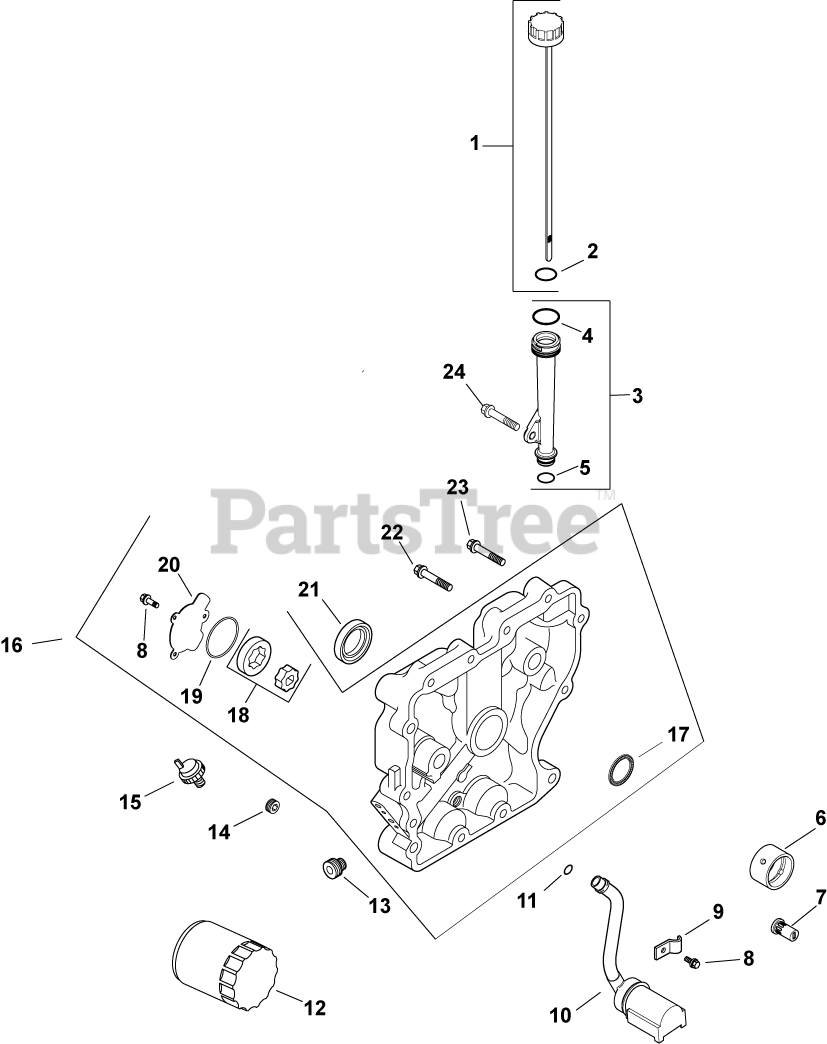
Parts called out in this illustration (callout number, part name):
1	KIT, OIL FILL CAP ASSEMBLY
2	O-RING - USE 25 153 02-S
3	KIT, OIL FILL TUBE - USE 12 755 113-S
4	O-RING, UPPER OIL FILL TUBE
6	BEARING, CRANKSHAFT
7	VALVE, OIL PRESSURE RELIEF
8	SCREW,FLG THD FRM M5X0.8X16-(#25086398S)
10	KIT, OIL PICK-UP
11	O-RING (.5" DIA)
12	OIL FILTER
13	NIPPLE, OIL FILTER
14	PLUG, CTSK PIPE 1/8"
15	SWITCH, PRESSURE (CLOSED)-USE 25 099 27-
16	PLATE, CLOSURE & BEARING
17	O-RING (1.78" DIA)
18	PUMP ASSEMBLY, OIL
19	O-RING (1.78" DIA)
20	COVER, OIL PUMP
21	SEAL, OIL
22	SCREW, FLG M8X1.25X45
23	SCREW, HEX FLANGE -USE 24 086 17-S
24	SCREW, SPECIAL HEAD
